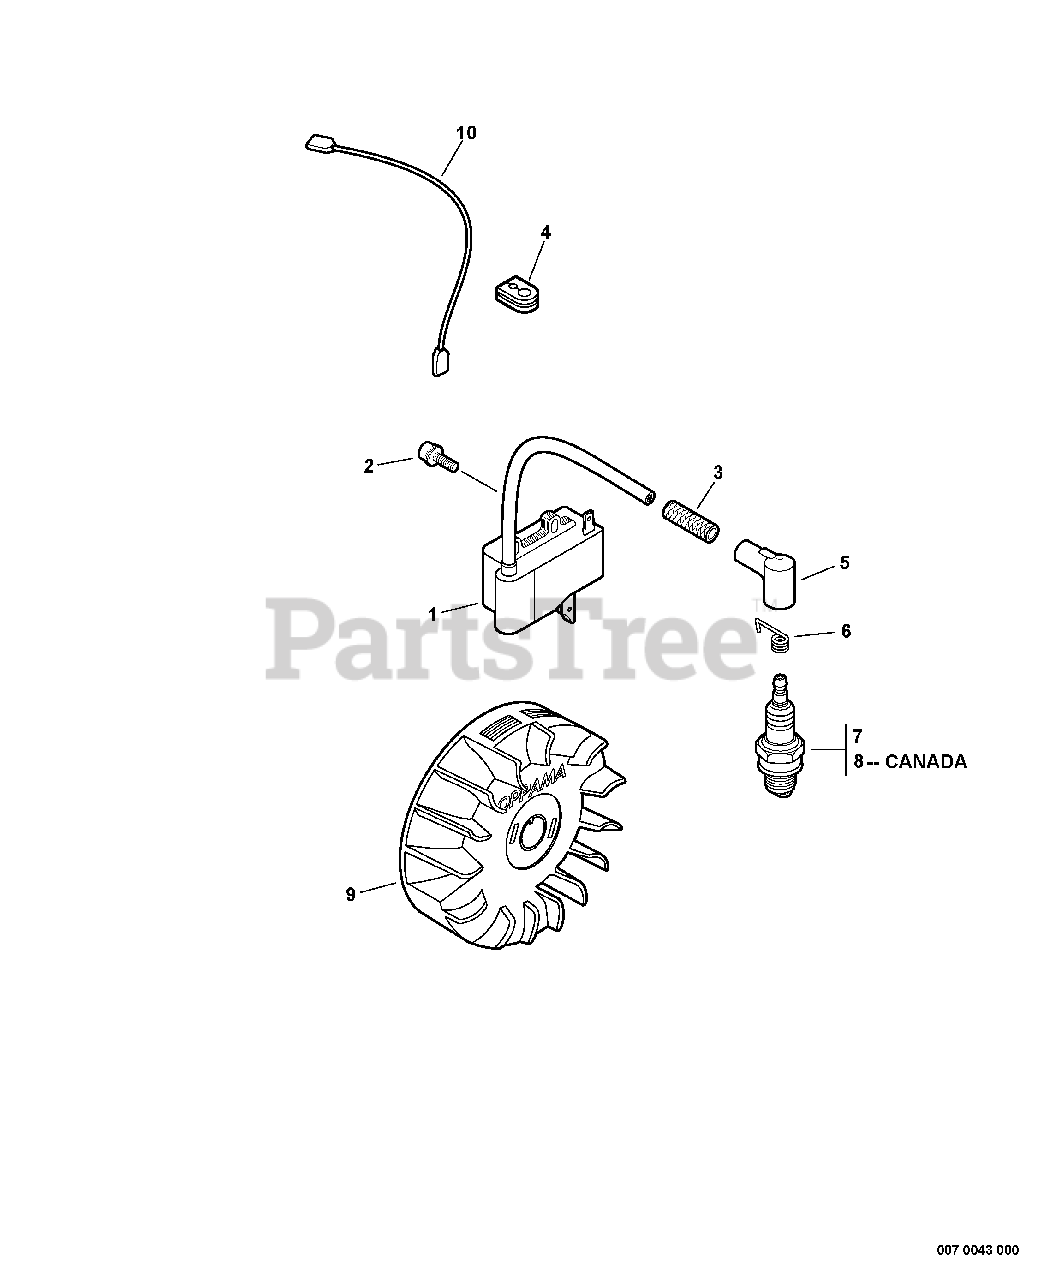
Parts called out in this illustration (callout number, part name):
1	COIL, IGNITION
2	SCREW - 4X20
3	TUBE, INSULATOR
5	CAP, SPARK PLUG
6	TERMINAL, SPARK PLUG CAP
7	SPARK PLUG -- BPM-8Y
8	SPARK PLUG -- BPMR-8Y
9	FLYWHEEL
10	LEAD - IGNITION
